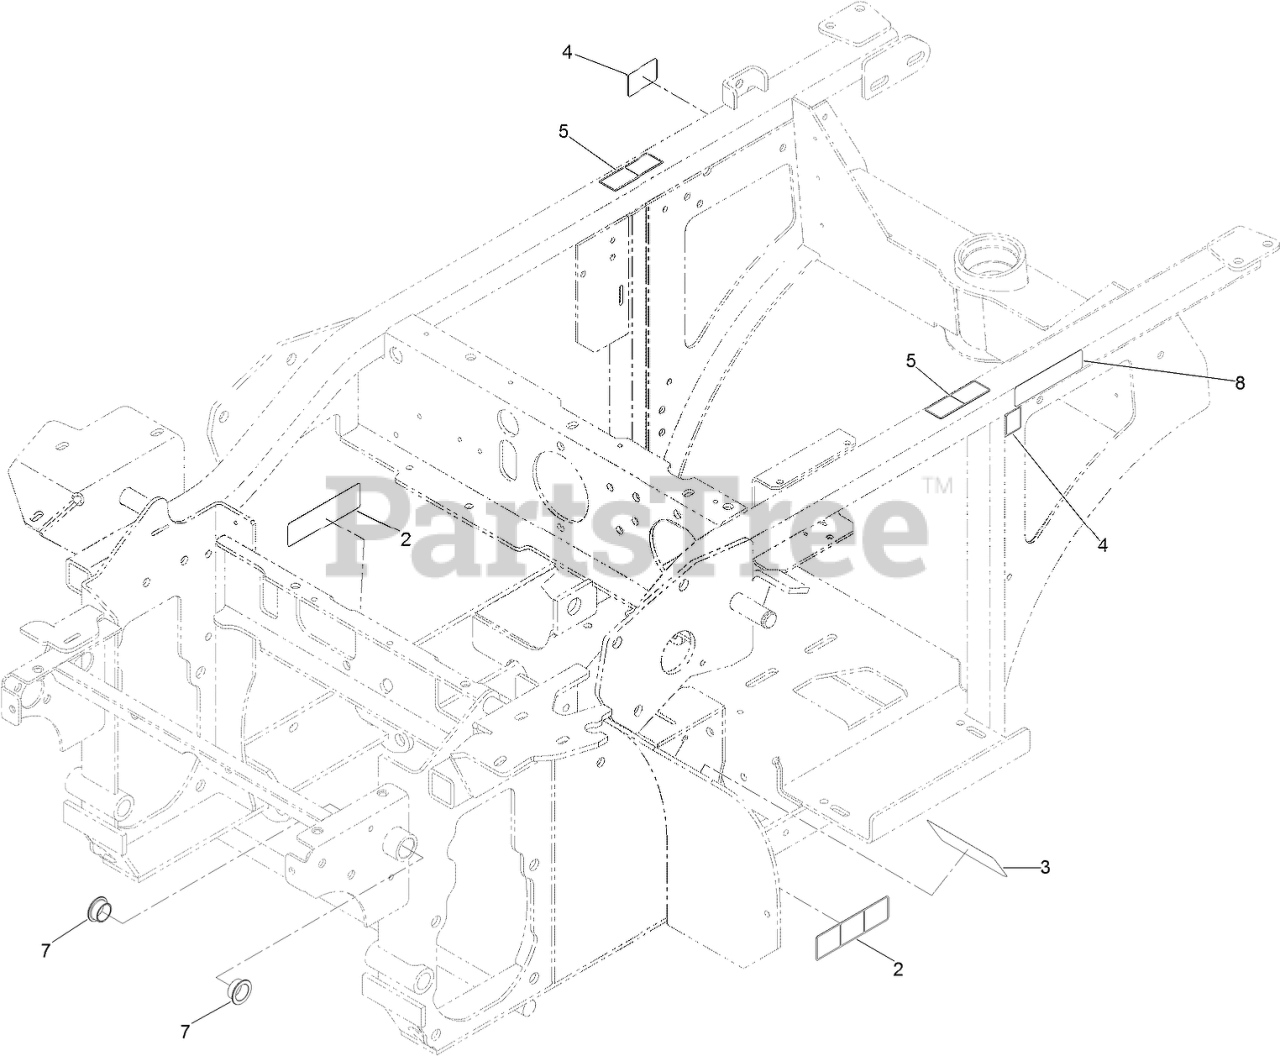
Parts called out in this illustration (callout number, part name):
2	DECAL-COVER, MISSING
3	Decal-Adjustment, Clutch
4	DECAL-WARNING
5	DECAL-WARNING, PINCH POIN
7	BUSHING-BRONZE
8	DECAL-ARRESTOR, SPARK
